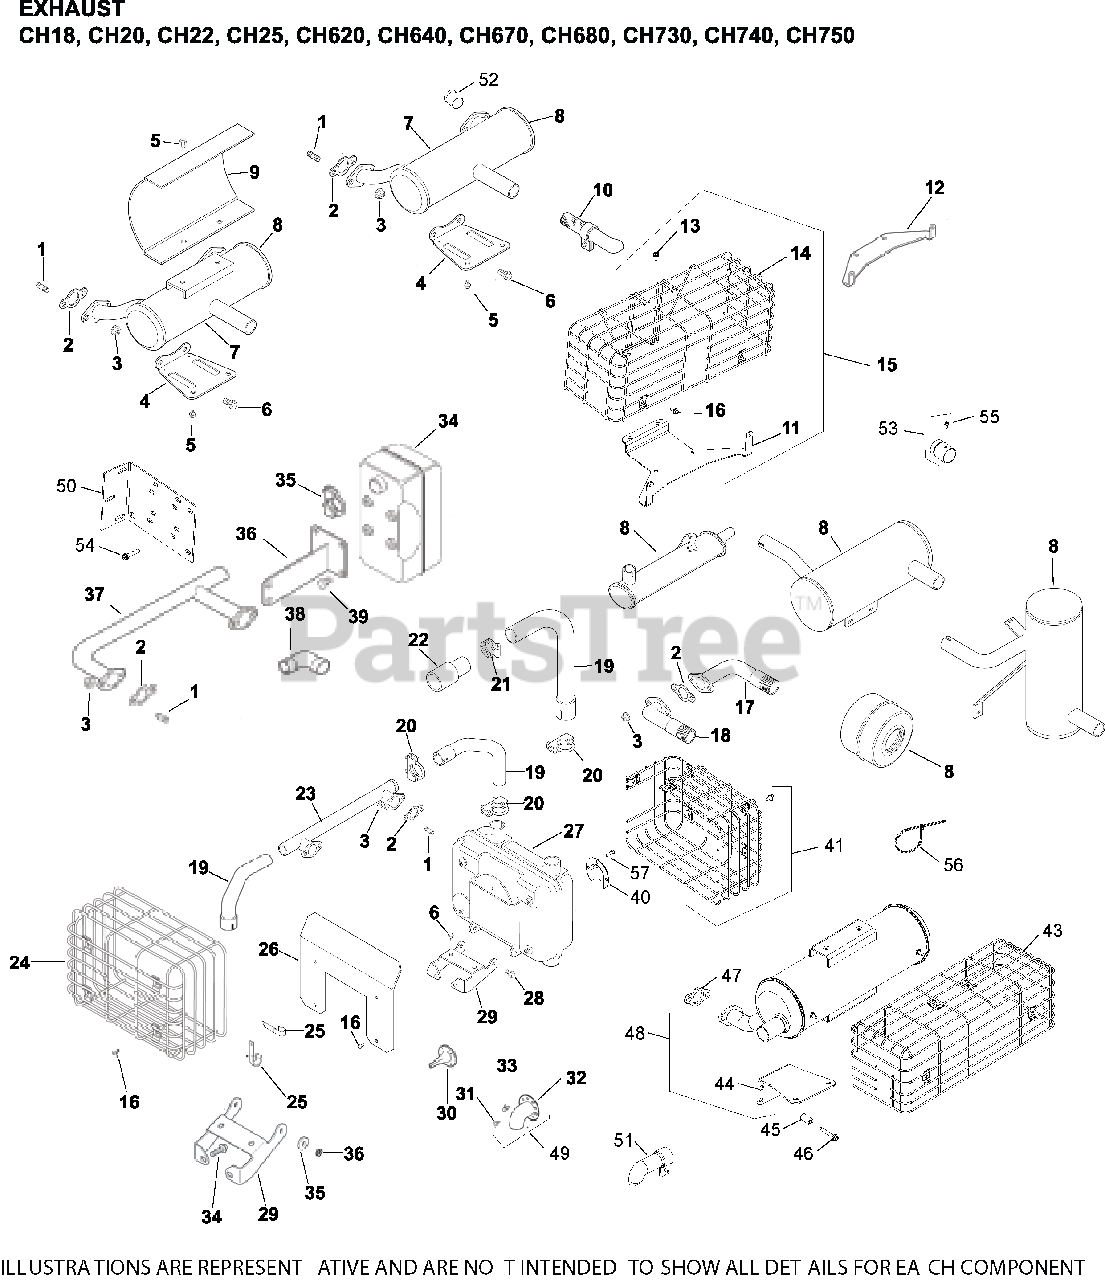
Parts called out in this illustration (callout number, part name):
2	GASKET, EXHAUST
3	NUT, FLG M8X1.25
6	SCREW, FLG M8X1.25X20
16	SCREW, THREAD FORMING
20	CLAMP, MUFFLER
26	SHIELD , MUFFLER
28	SCREW, THREAD FORMING
29	BRACKET, MUFFLER
37	MANIFOLD, EXHAUST
41	KIT, WIRE GUARD
